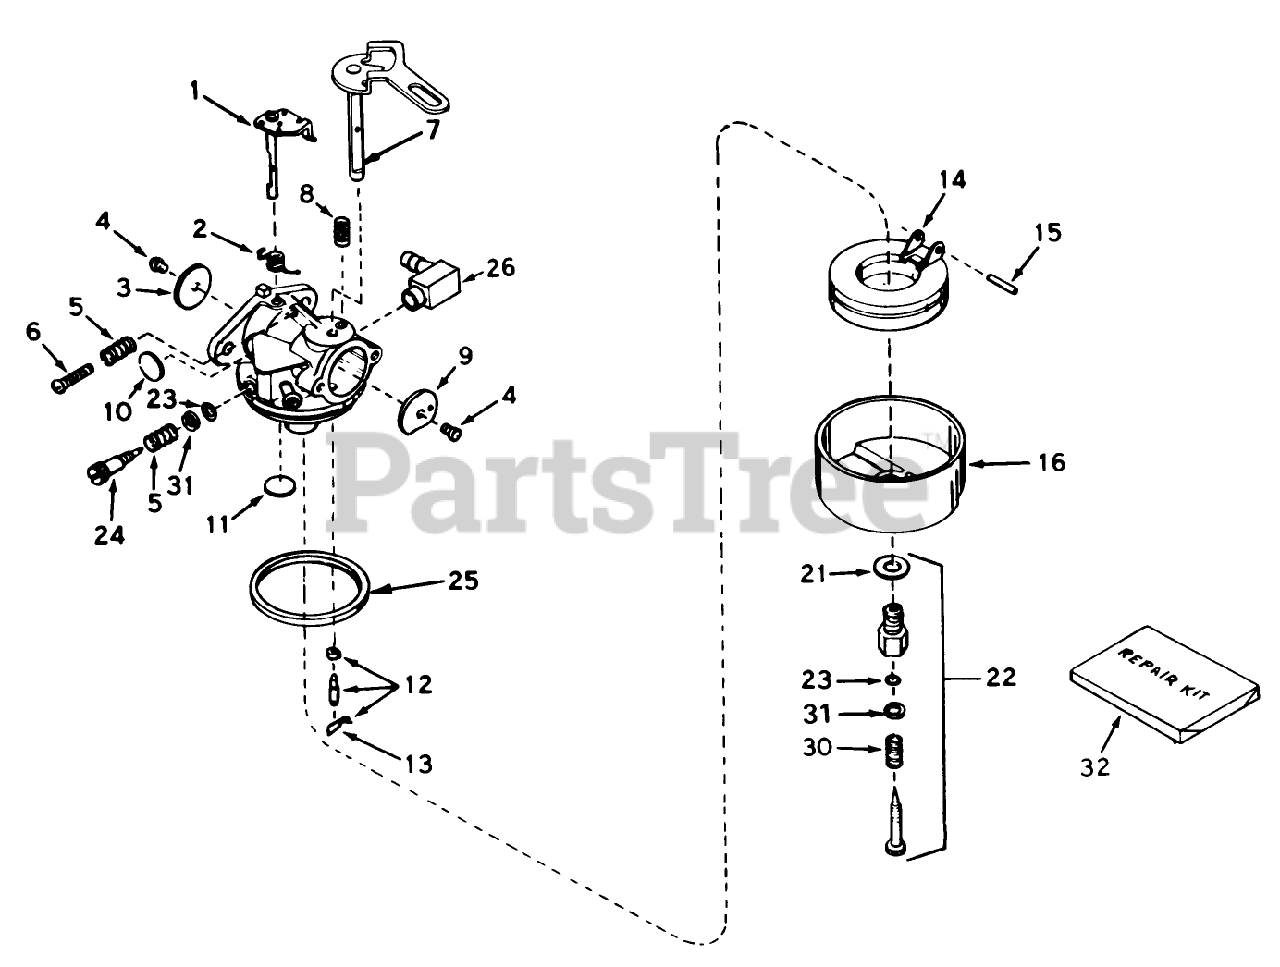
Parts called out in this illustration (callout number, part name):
1	Throttle Shaft and Lever ASM
2	Spring-Return, Throttle
3	Shutter-Throttle
4	Screw-Shutter
5	Spring-Tension
6	Screw-Throttle Crack Screw / Idle Speed
7	Choke Shaft and Lever Asm
8	Spring-Positioning, Choke
9	Shutter-choke
10	Plug-Welch, Idle Mixture Well
11	Plug-Welch, Atmospheric Vent
12	Inlet Needle, Seat Clip Assy. (Incl. No. 13)
13	Clip-Spring
14	Float
15	Shaft-Float
16	Bowl-Float (no drain)
21	Washer-Bowl Nut
22	Adjustment Screw Assy., Main (Incl. Nos. 5A, 21 23)
23	ORing
24	Screw, Idle Adj.
25	O Ring-Bowl, Float
26	Fitting-Fuel
30	Spring
31	Washer
32	Repair Kit (Incl. items marked *)
